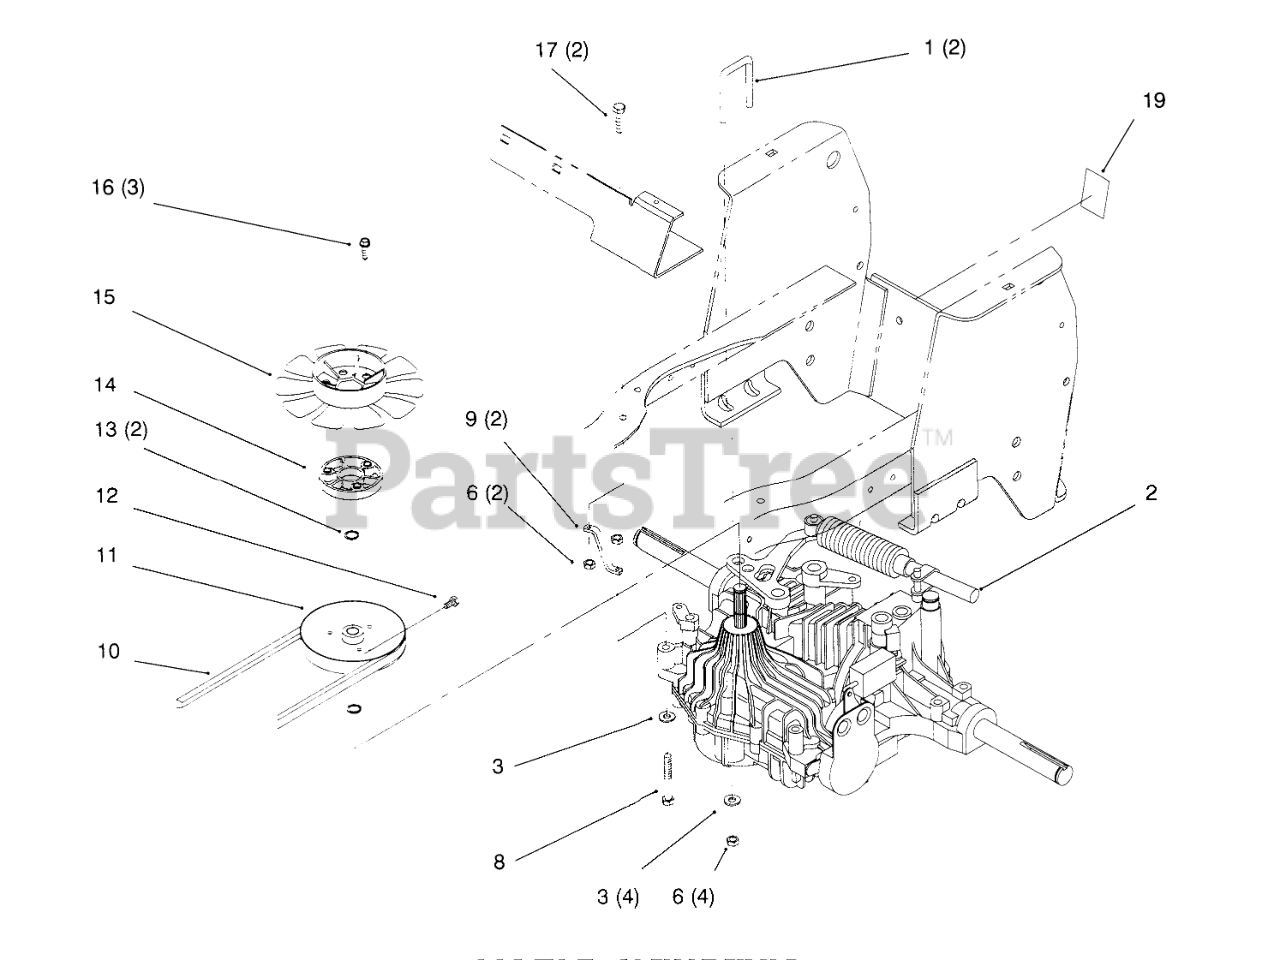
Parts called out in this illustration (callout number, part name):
1	U-Bolt (Only On: 72043,72063,72103)
2	Transaxle-Tuff Torq K61 (Only On: 72043,72063,72103)
3	Washer-Flat (Only On: 72043,72063,72103)
6	Nut-Lock (Only On: 72043,72063,72103)
8	Screw HH (Only On: 72043,72063,72103)
9	Strap-Torque (Only On: 72043,72063,72103)
10	Belt-Hydro (Only On: 72043,72063,72103)
11	Pulley (Only On: 72043,72063,72103)
12	Screw-Set (Only On: 72043,72063,72103)
13	Snap Ring (Only On: 72043,72063,72103)
14	Spacer-Fan (Only On: 72043,72063,72103)
15	Fan (Only On: 72043,72063,72103)
16	Screw-HH (Only On: 72043,72063,72103)
17	Screw-HH (Only On: 72043,72063,72103)
19	Decal-Hydro Valve (Only On: 72043)
19	Decal-Bypass (Only On: 72063,72103)
